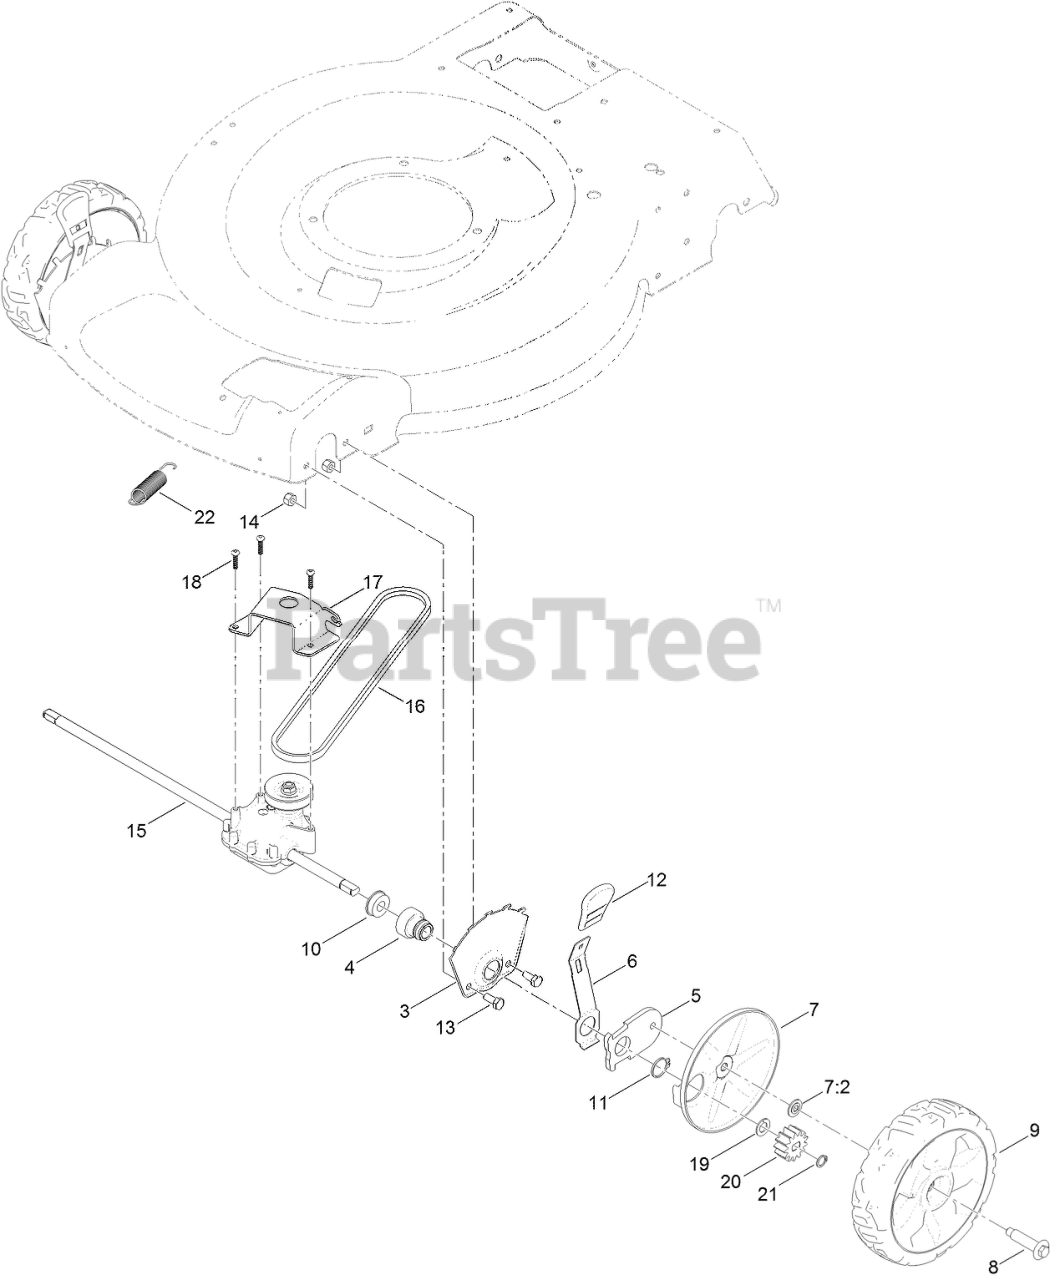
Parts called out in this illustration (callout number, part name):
3	PLATE-HOC, FRONT
4	RETAINER-BEARING, HOC
5	ARM-PIVOT, FRONT
6	Arm-Spring
7	WHEEL COVER ASM
7:2	WASHER-STEPPED
8	BOLT-SHOULDER
9	8 INCH WHEEL ASM (FRONT)
10	BEARING-BALL
11	RING-RETAINING
12	KNOB-HOC
13	SCREW-HH
14	NUT-LOCK, NI
15	TRANSMISSION ASM
16	V-BELT
17	BRACKET-TRANSMISSION
18	SCREW-PLASTITE
19	WASHER-THRUST
20	GEAR-PINION, 13T
21	RING-RETAINING
22	SPRING-EXTENSION
